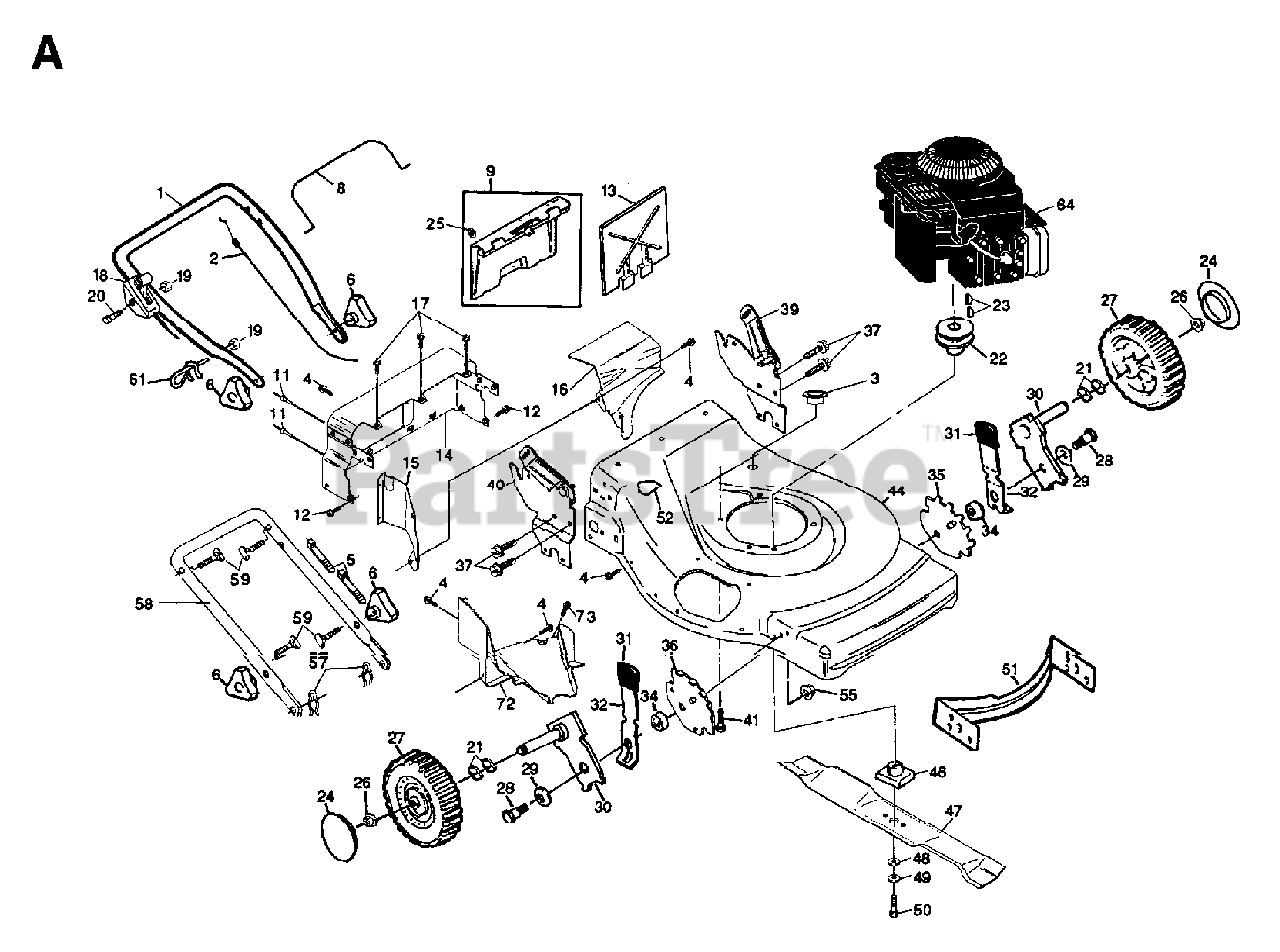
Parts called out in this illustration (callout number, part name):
2	CABLE-ZONE
4	SCREW.HXTAP.10-24
5	CLIP CABLE SNAP
6	HANDLE KNOB
8	CONTROL BAR
11	RIVET BLIND
13	MULCHER PLUG
15	SIDE BAFFLE
16	DISCHARGE BAFFLE
18	THROTTLE CONTROL
19	NUT
20	SCREW 1/4-20X1.75
21	WAVE WASHER
22	ENGINE.PULLEY.FWG
23	HI PRO KEY PM
24	CAP.HUB.ARC.SPOKE.8".LP
26	HEX FLANGE LOCKNT
28	BOLT
29	BELLEVILLE WASHER
30	AXLE ARM
31	SELECTOR KNOB
32	SELECTOR SPRING
34	RP SPACER HT ADJ
37	SELF-TAPPING SCREW 5/16-18X3/4
41	BOLT 3/8-16X1-1/8
46	RP BLADE ADAPTOR
47	%BLADE, MULCH
48	WASHER,HARDEN
49	LOCKWASHER
50	SCREW, HEX HD 3/8-24 X 1-3/8
52	DECAL MOWER CUT/FINGER
55	LOCKNUT PM
57	HAIRPIN COTTER
59	HANDLE BOLT
61	ROPE GUIDE
72	BAFFLE BELT COVER
73	SCREW.HX.13X.750
